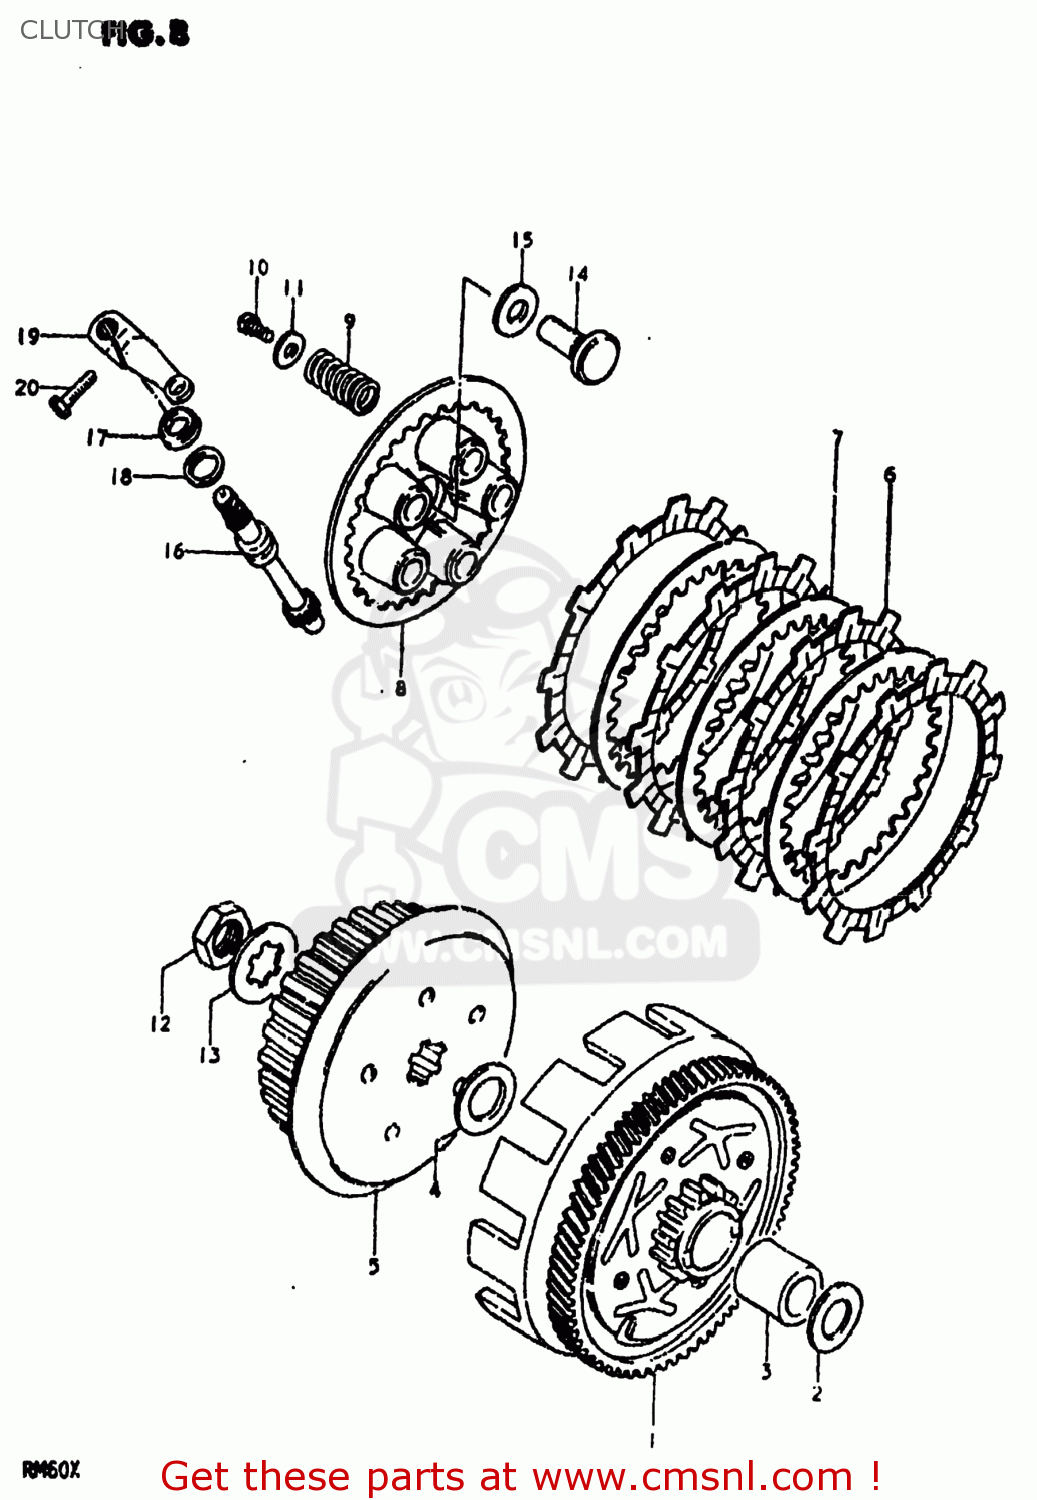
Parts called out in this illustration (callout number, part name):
1	GEAR ASSEMBLY,PRIMARY DRIVE
2	WASHER,THRUST
3	SPACER(17X22X28.5)
4	WASHER
5	HUB,CLUTCH SLEEVE
6	PLATE,CLUTCH DRIVE
7	PLATE,CLUTCH DRIVEN (NAS)
8	DISC,CLUTCH PRESSURE
9	SPRING
10	BOLT(5X16)
11	WASHER (5.5X16X1.2)
12	NUT
13	WASHER,LOCK
14	RACK,CLUTCH RELEASE
15	BEARING(10X22X2.8)
16	PINION,CLUTCH RELEASE
17	OIL SEAL
18	WASHER (12X17X1)
19	ARM,CLUTCH RELEASE
20	BOLT, UPPER
